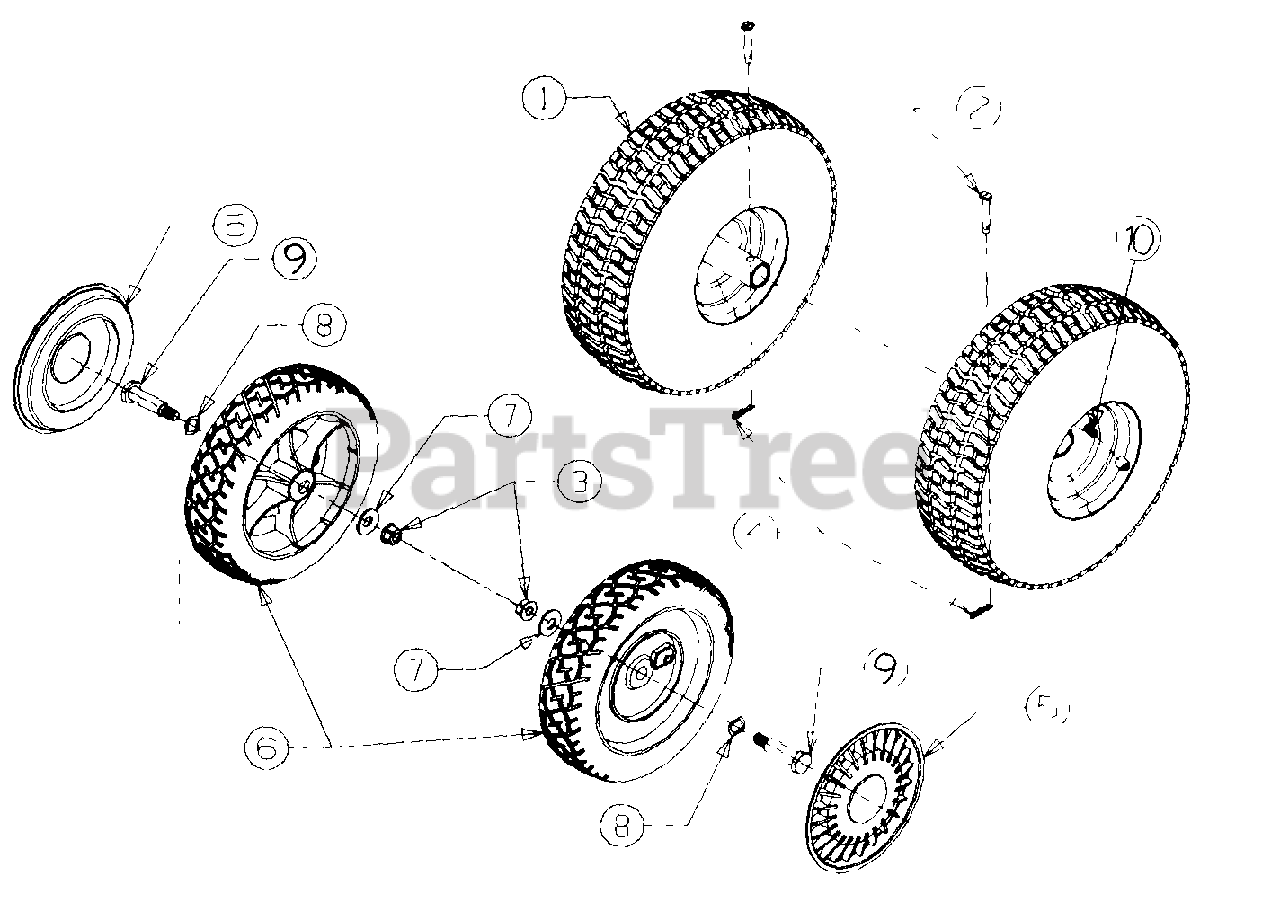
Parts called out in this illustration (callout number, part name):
1	WHEEL ASSY COMPLETE
2	PIN-CLEVIS
3	NUT-HEX FLANGE
4	PIN-COTTER
5	HUB CAP
6	WHEEL
7	WASHER-BELL
8	WASHER-WAVE
9	SCREW-SHOULDER
10	VALVE STEM
